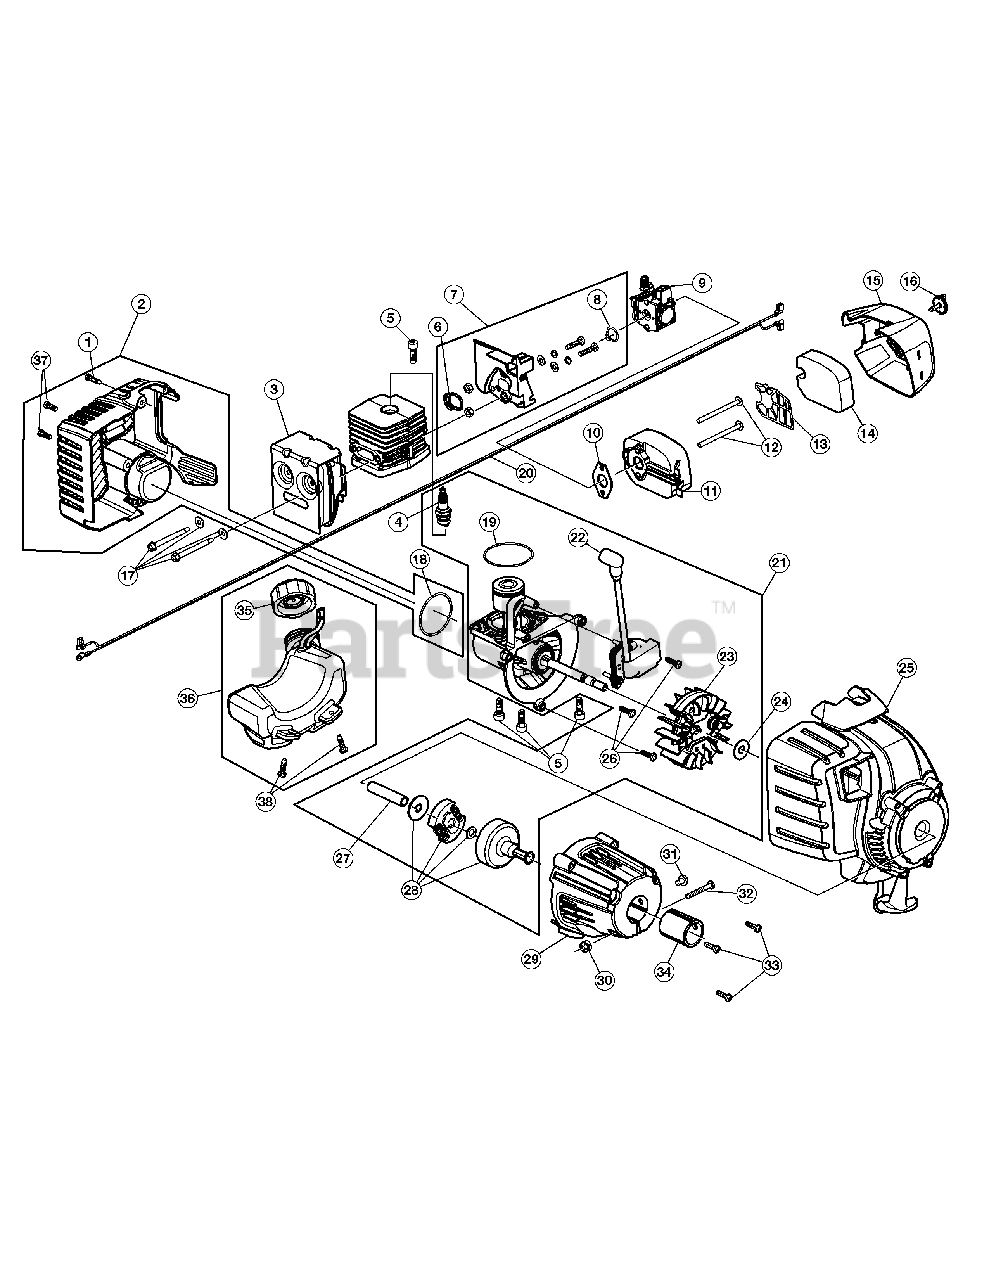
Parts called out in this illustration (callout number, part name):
2	Housing, Rear (Incl. 1, 18 & 37)
3	Muffler
4	Spark Plug
6	O-Ring
7	Insulator Assembly (Incl. 6 & 8)
8	O-Ring
9	Carburetor
10	Gasket
11	Air Cleaner Base
14	Filter
15	Air Cleaner Cover
17	Muffler Screw
18	O-Ring
19	O-Ring
20	Lead Wire
21	Shortblock (Incl. 4, 19, 22-24 & 26-28)
22	Module
23	Flywheel
24	Washer
25	Housing, Starter
26	Screw
27	Spacer
28	Clutch Assembly
29	Clutch Cover
32	Screw
34	Spacer, Rubber
35	Fuel Cap
36	Fuel Tank (Incl. 35 & 38)
37	Screw
38	Fuel Tank Screw
